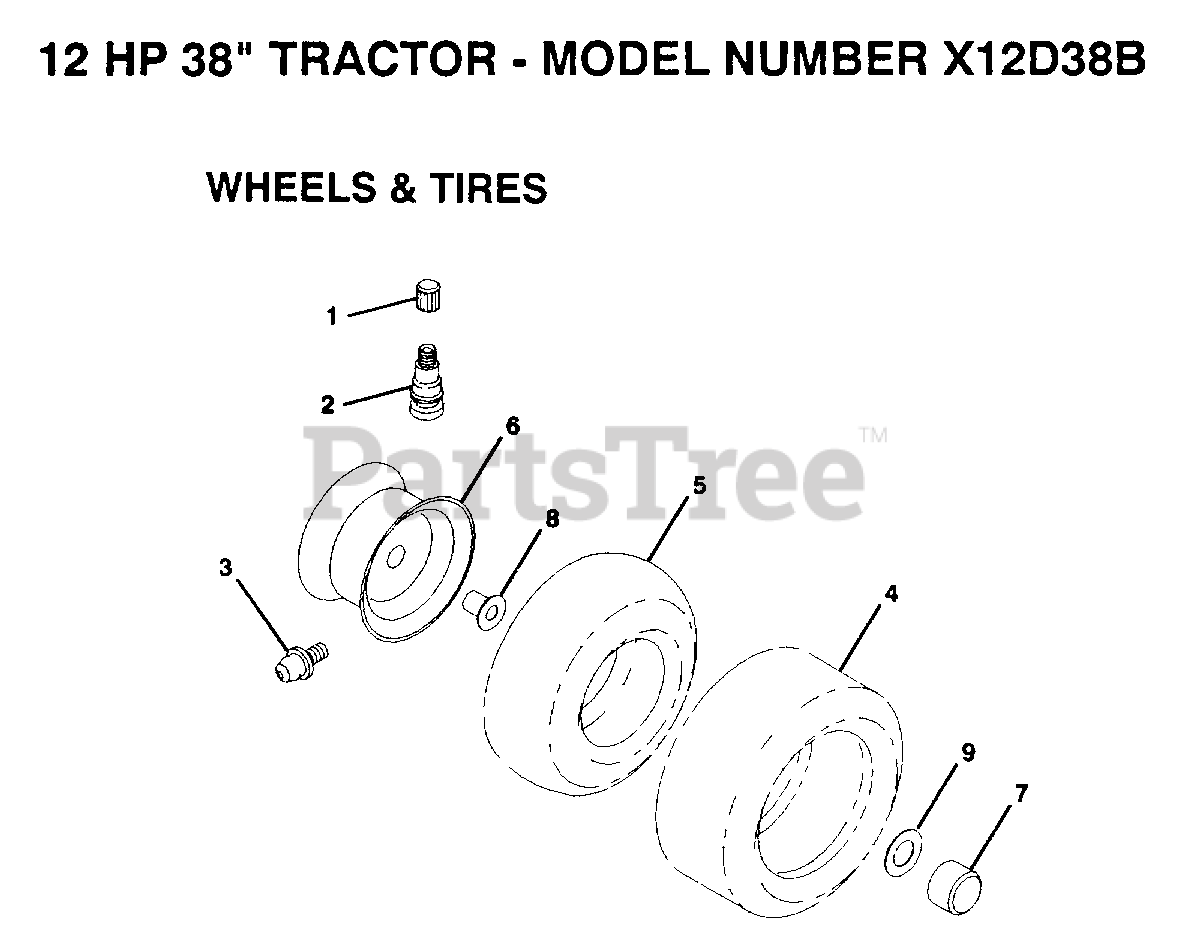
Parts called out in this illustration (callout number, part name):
1	VALVE CAP
2	VALVE STEM LT
3	FITTING LT
5	TUBE.18X9.5-8
5	TUBE.5.3/4.5/6
7	HUB CAP
8	"FLANGE, BEARING"
9	WASHER
